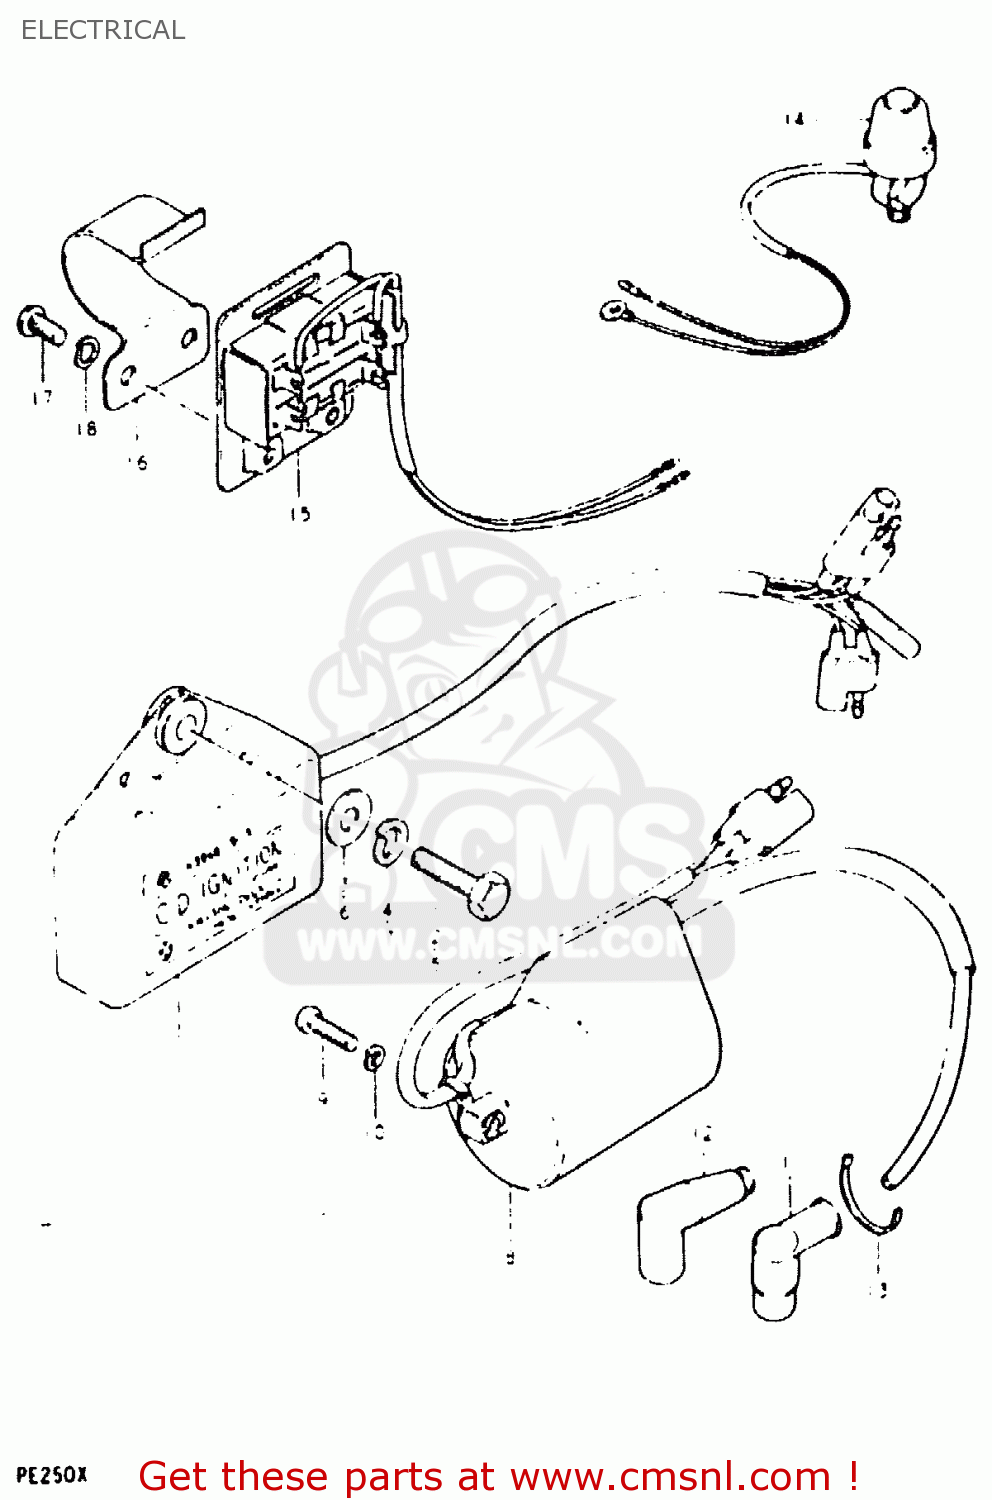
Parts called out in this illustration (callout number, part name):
1	CDI UNIT ASSEMBLY
5	BOLT 6X22
6	WASHER
7	LOCK WASHER
8	COIL ASSEMBLY,IGNITION
9	SCREW 5X20
10	LOCK WASHER
12	CAP, SPARK PLUG
13	CLAMP
14	SWITCH ASSEMBLY
